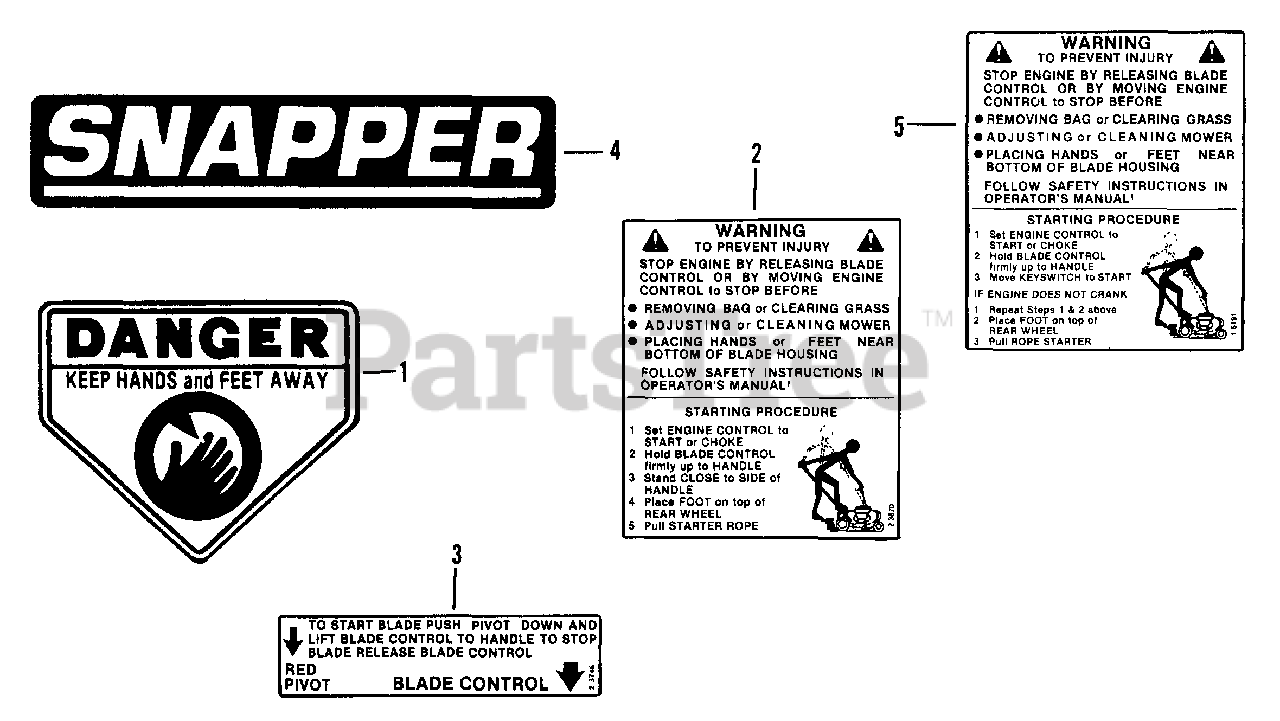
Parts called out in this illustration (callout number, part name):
1	DECAL, CPSC (Danger)
2	DECAL, Warning & Starting
3	DECAL, Blade Start
4	DECAL, SNAPPER
5	DECAL, Warning & Starting
